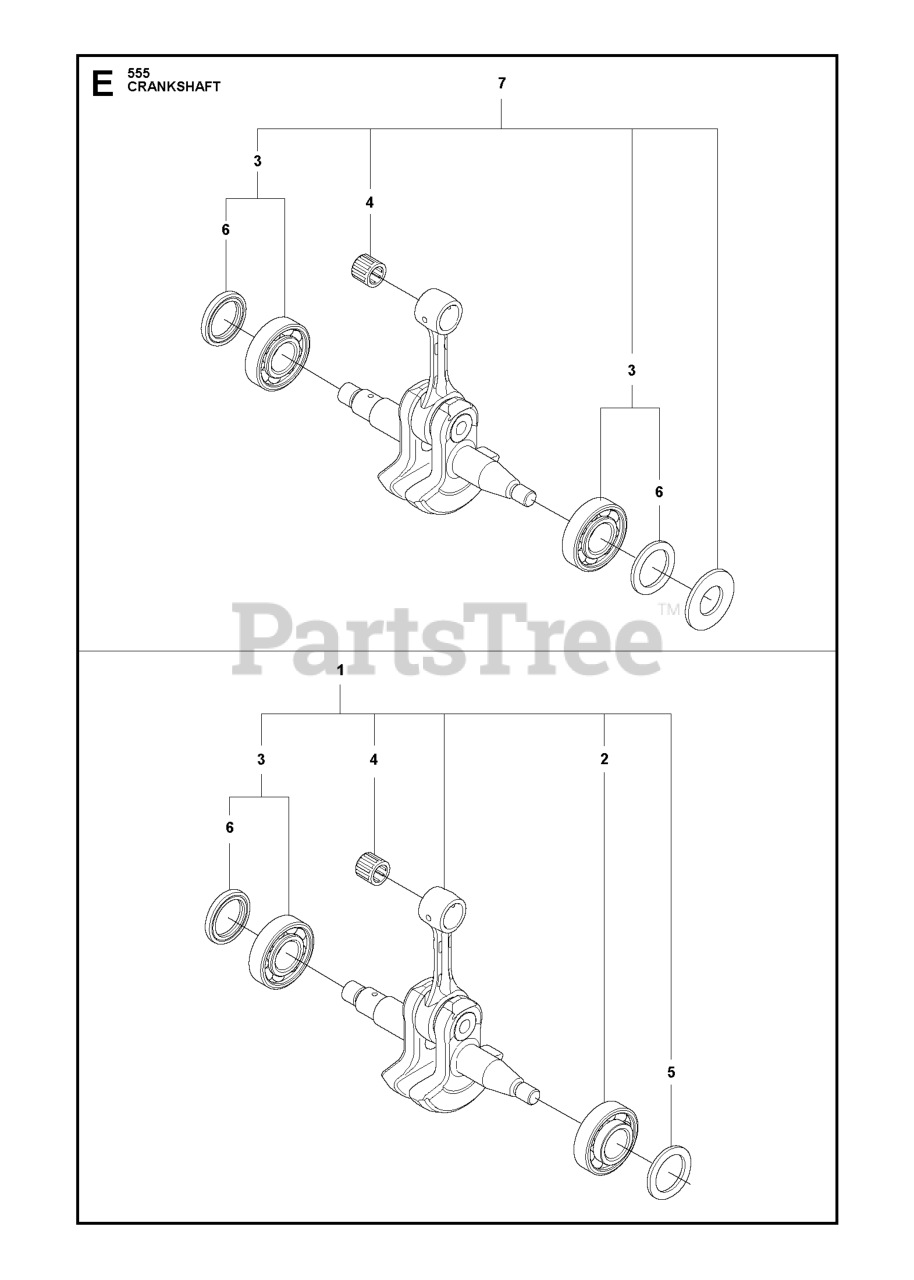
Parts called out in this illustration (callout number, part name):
1	CRANKSHAFT ASSY
2	BEARINGS
4	SUPPORT BUSHING
5	RADIAL SEAL
6	RADIAL SEAL
7	CRANKSHAFTS
